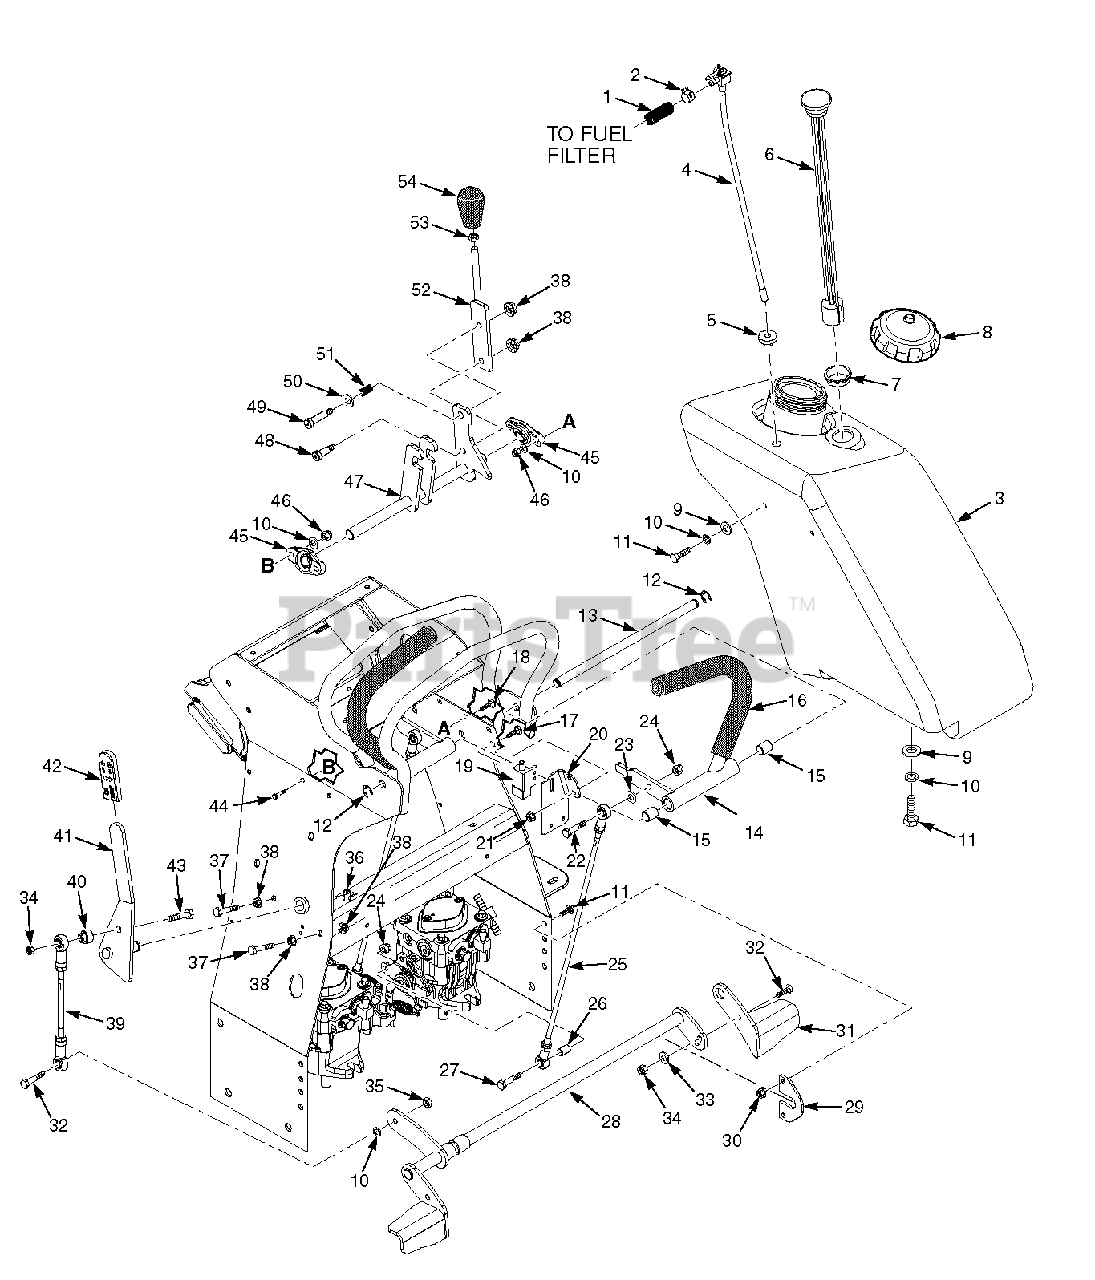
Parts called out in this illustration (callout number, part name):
1	Fuel Hose 1/4" ID
2	Clamp, Fuel Hose 1/4" ID
3	Fuel Tank Assy.
4	Valve, Fuel Shut Off
5	Bushing, .56 Viton
6	Fuel Gauge Assembly
7	Grommet, Fuel Gauge
8	Cap, Fuel Tank
9	Flatwasher, 5/16-.375 x .875 x .083
10	Lockwasher, 5/16" Spring
11	Bolt, Hex Heaf 5/16-18 x 3/4"
12	Retaining Ring, .50 External
13	Shaft, Steering Handles
14	Handle Bar Assy., LH
15	Bearing
16	Grip, Control Lever
17	Bolt, Carriage 1/4-20 x 3/4"
18	Bolt, Carriage 1/4-20 x 1"
19	Switch, Interlock
20	Bracket, Neutral Switch
21	Nut, Serrated Flange 1/4-20
22	Bolt, Hex Head 5/16-18 x 1-1/4"
23	Flatwasher, 5/16-.344 x .688 x .065
24	Nut, Elastic Stop 5/16-18
25	Linkage Assembly
26	Spacer, Pump
27	Bolt, Hex Head 5/16-18 x 1-3/4"
28	Bellcrank, Brake Weldment
29	Brake Keeper Plate - SVR-61V
30	Nut, Serrated Flange 5/16-18
31	Brake Weldment, LH
32	Bolt, Hex Head 3/8-16 x 1-1/4"
33	Flatwasher, 3/8-.438 x 1.0 x .083
34	Nut, Elastic Stop 3/8-16
35	Nut, Center Lock 3/8-16
36	Retaining Ring, .625 External "E"
37	Bolt, Hex Head 5/16-18 x 1-1/2"
38	Nut, Serrated Flange 5/16-18
39	Linkage Assembly, Brake
40	Spacer
41	Brake Lever w/Grip - SVR-61V
42	Grip, Brake Lever
43	Bolt, Hex Head 3/8-16 x 2"
44	Bolt, Hex Head 1/4-20 x 1"
45	Bearing
46	Nut, Elastic Stop 1/4-20
47	Lock Weldment, Neutral
48	Bolt, Shoulder 3/8 x .375
49	Bolt, Shoulder 3/8 x 1"
50	Flatwasher, 3/8-.406 x .812 x .065
51	Spring, Neutral Lever
52	Handle Weldment
53	Nut, Jam 3/8-16
54	Knob, Soft Touch
